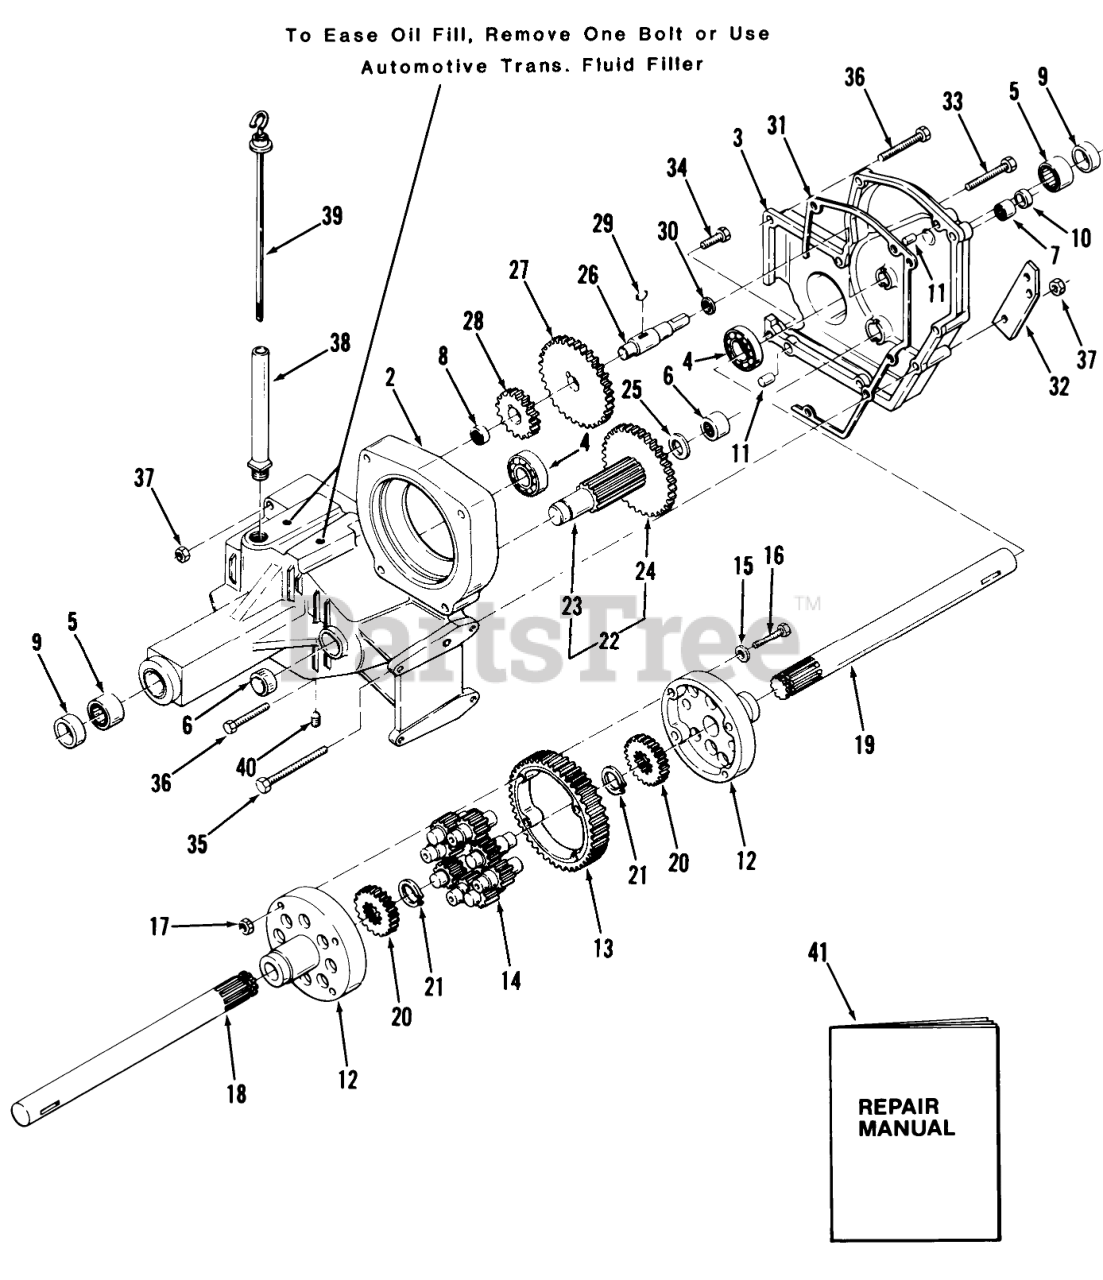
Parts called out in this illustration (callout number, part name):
2	CASE TRANS RH
3	CASE TRANS LH
4	BEARING-BALL
5	BEARING
6	BEARING-NEEDLE
7	NEEDLE BEARING
8	BEARING-NEEDLE
9	SEAL-OIL
10	Seal
11	PIN-LOCATING
12	END CAP-DIFFERENTIAL
13	GEAR-DIFFERENTIAL RING, 43T
14	GEAR-PINION, 11T
15	WASHER
16	BOLT-HEX
18	AXLE-REAR RH
19	AXLE-REAR LH
20	GEAR-AXLE DIFFERENTIAL
21	RING-SNAP
22	ASSY GEAR
22	GEAR ASM
23	PINION SHAFT
24	GEAR 46T
25	WASHER-THRUST
26	SHAFT GEAR
27	GEAR 46 TEETH
27	Gear 44 Tooth
28	GEAR 20 TEETH
28	GEAR 22T
29	Key
30	Race Thrust
31	GASKET-TRANSMISSION
32	BRACKET-BRAKEB
33	Bolt
34	Bolt
35	Hex Bolt
36	Screw-Hex. Hd.
37	Nut
38	NIPPLE-TRANS FILL
39	ASSY-DIPSTICK
39	Dipstick
40	PLUG 1/4 PIPE ALLEN
41	Repair Manual
